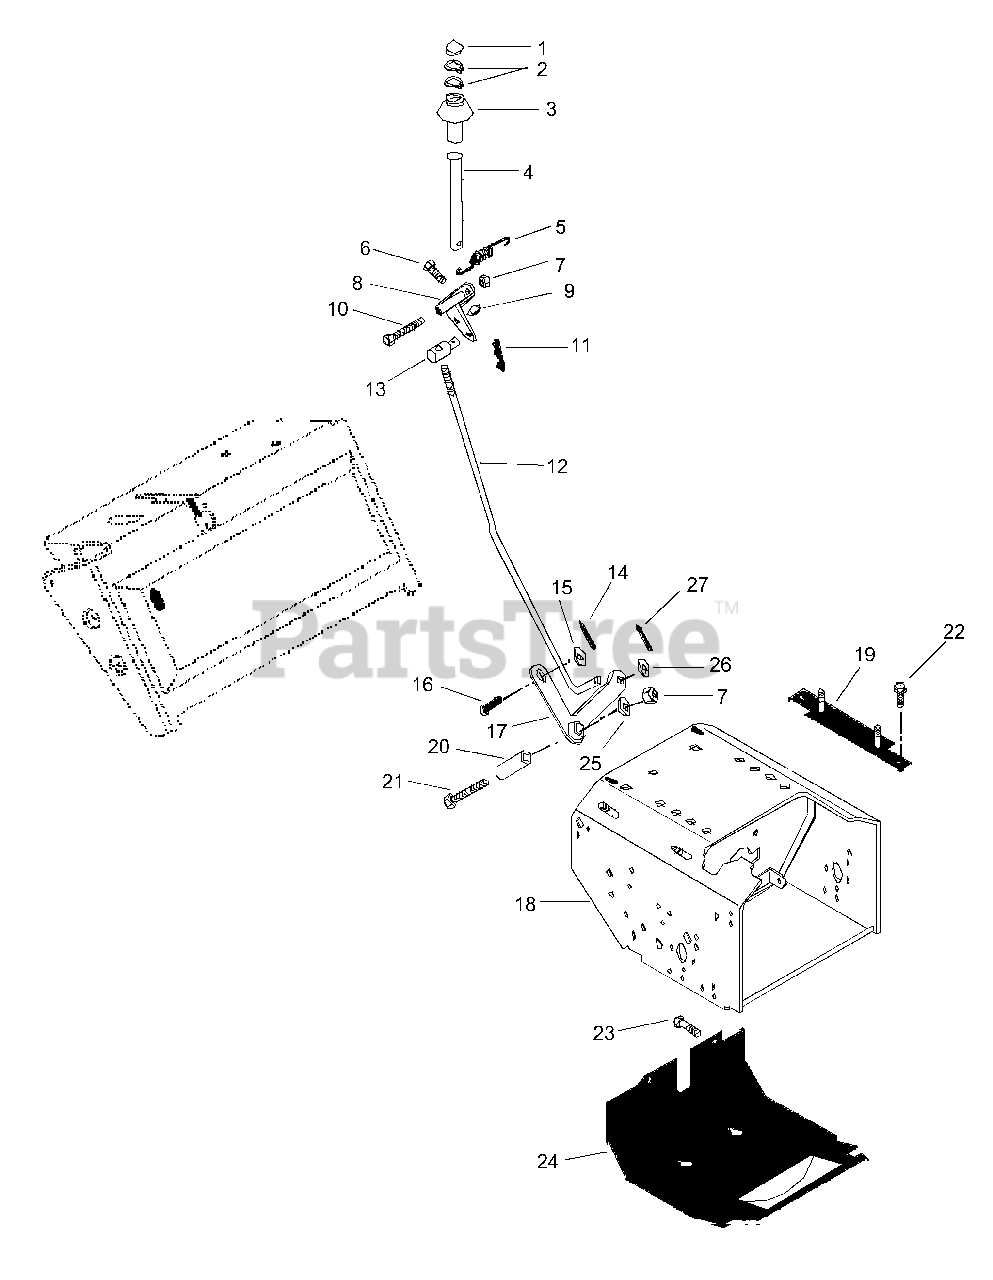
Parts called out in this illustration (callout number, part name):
1	HOLE PLUG
2	RG-RTNG-EXT .500X.015
4	ROD
5	SG-TENS .055X.33X1.31 WLD 7
6	@BLT-HEX .25-20X1.00 GR5 YWZC
7	NUT-HEX .312-24 YWZC
9	@NUT-LK-CTR .25-20 YWZC
10	@BLT-HEX .31-18X3.50 GR5 YWZC
11	PIN-HAIR INT .08X.18X1.18 YWZC
12	ROD, SHIFT
13	PIVOT, ROD
14	@PIN-CTR .09X.75 EXTPRSQCT YWZ
15	WSHR-FL-STL .382X.812X.023YWZC
16	CLEVIS PIN
17	ARM, SHIFT
18	FRAME, MAIN
19	BOLT STRAP
20	BSHG-SLV .328X.50X.75
21	@BLT-HEX .31-18X1.25 GR5 YWZC
22	@SCR-TAP .25-20X.37 HWH YWZ TR
23	@SCR-TAP .31-18X.50 HWH TR YWZ
24	COVER, BOTTOM
25	@WSHR-FL-STL.344X.688X.065YWZC
26	@WSHR-FL-STL.531X1.06X.095YWZC
27	@PIN-CTR .12X.75 EXTPRSQCT YWZ
